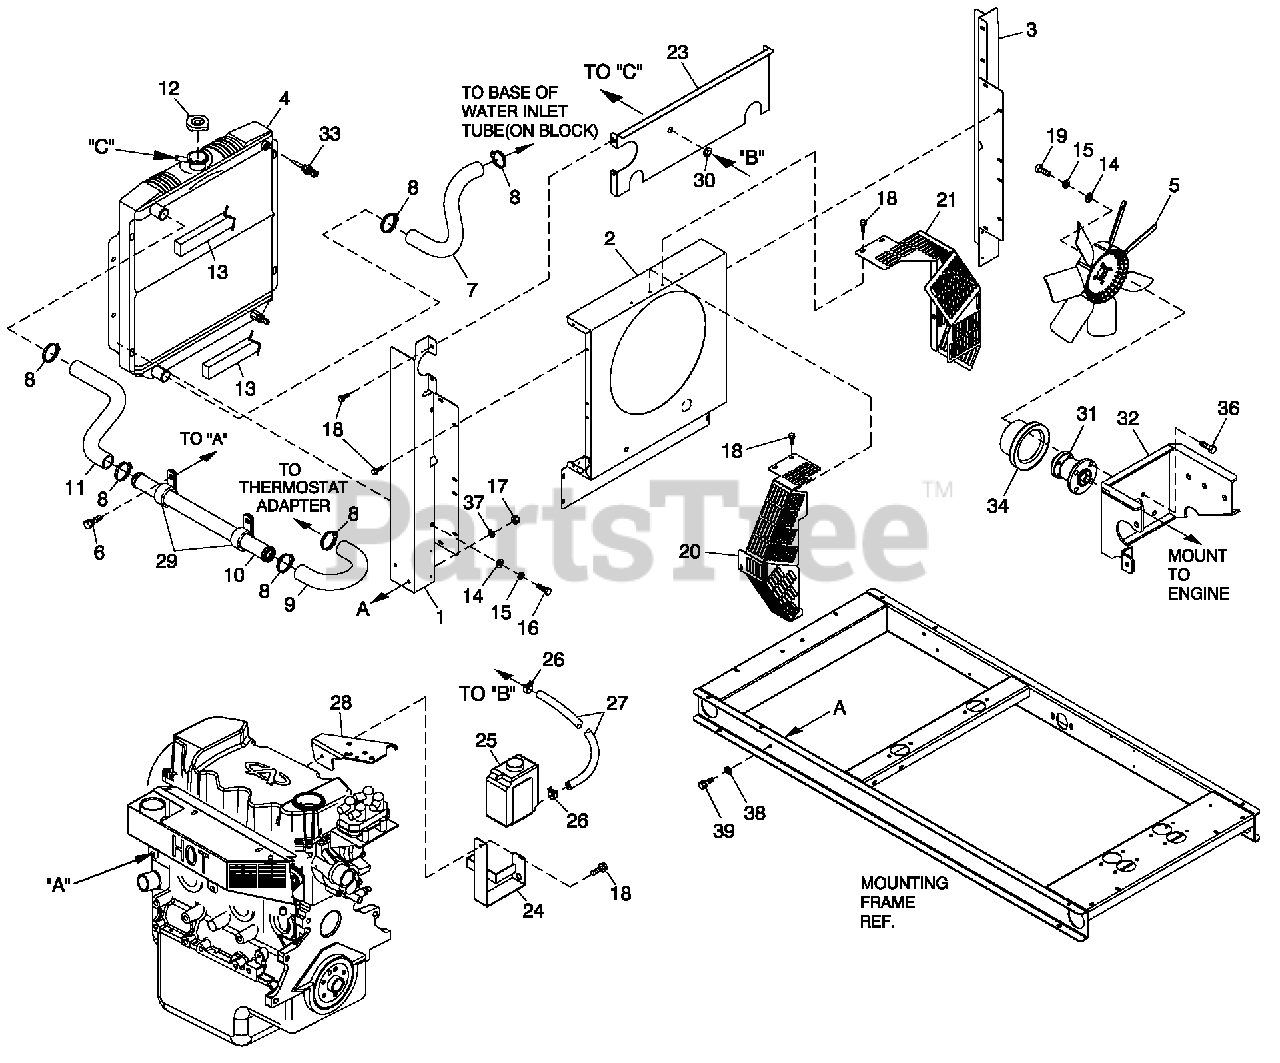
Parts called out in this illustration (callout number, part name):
1	RADIATOR SUPPORT LH SIDE 1.6L
2	VENTURI 1.6L
3	RADIATOR SUPPORT RH SIDE 1.6L
4	RADIATOR 1.6L CHY
5	FAN COOL 450MM DIA 7 BLADE
6	SCREW HWHTF M6-1.0X16
7	HOSE LOWER RADIATOR 1.6L
8	CLAMP HOSE #24 B1.06-2.00
9	HOSE REAR COOLANT 1.6L
10	TUBE ENGINE COOLANT 1.6L
11	HOSE UPPER RADIATOR 1.6L
12	CAP RADIATOR
13	TAPE FOAM 1 X 1 (24" LG)
14	WASHER FLAT 1/4- M6ZINC
15	WASHER LOCK M6-1/4
16	SCREW HHFC M6-1.0X20 G8.8
17	NUT HEX M8-1.25 G8 CLEAR ZINC
18	SCREW THF M6-1 X 12 N WA Z/JS
19	SCREW HHC M6-1.0X 20 G8.8
20	GUARD FAN LH C1
21	GUARD FAN RH C1
23	RADIATOR BLOCK-OFF
24	BRACKET COOLANT TANK
25	TANK COOLANT RECOVERY
26	CLAMP HOSE BAND 1/4
27	HOSE 9/32 ID (43" LG)
28	BRACKET STEPPER MOTOR COOLANT
29	CLAMP VINYL 1.31 X.281 Z
30	GRO M MET 5/8"X 11/8"X 5/16"
31	ASSY FAN BEARING SUPPORT
32	BRACKET FAN ALT ADAPTER 1.6L
33	PROBE COOLANT LEVEL 3/8 NPTF
34	PULLEY-FAN 95 DIA
35	TIE WRAP UL 7.4" X .19" BLK
36	SCREW HHC M8-1.25X 16 G8.8
37	WASHER SHAKEPROOF EXT 5/16 STL
38	WASHER LOCK M8-5/16
39	SCREW HHC M8-1.25X 20 G8.8
